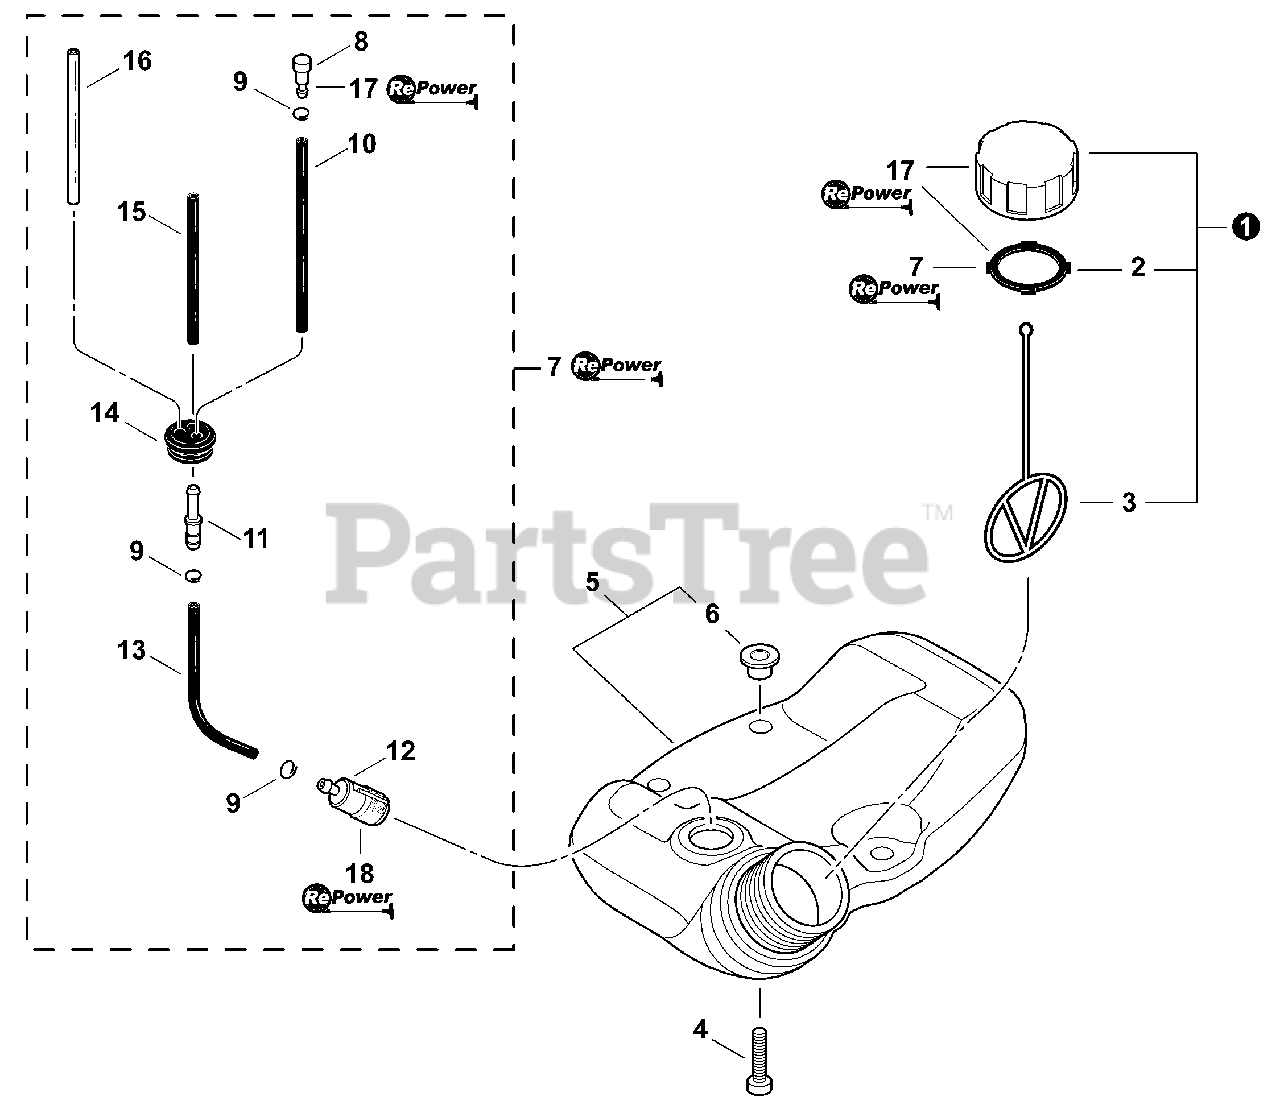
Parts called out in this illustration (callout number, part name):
1	CAP ASSY, FUEL
2	GASKET, FUEL CAP
3	CONNECTOR, CAP L= 123
4	BOLT, TORX 5×20
5	TANK ASSY, FUEL
6	COLLAR 5
7	FUEL SYSTEM KIT
8	VENT ASSY
9	CLIP Ø6
10	PIPE, FUEL 3×5×90 BLACK
11	CONNECTOR, PIPE Ø5ר3.5
12	FILTER, FUEL
13	PIPE, FUEL 3×5×130 BLACK
14	GROMMET, FUEL Ø5
15	PIPE, FUEL 3×5×74 BLACK
16	PIPE, FUEL 3×6×80 CLEAR
17	CAP/VENT KIT - REPOWER
18	TUNE-UP KIT - REPOWER
